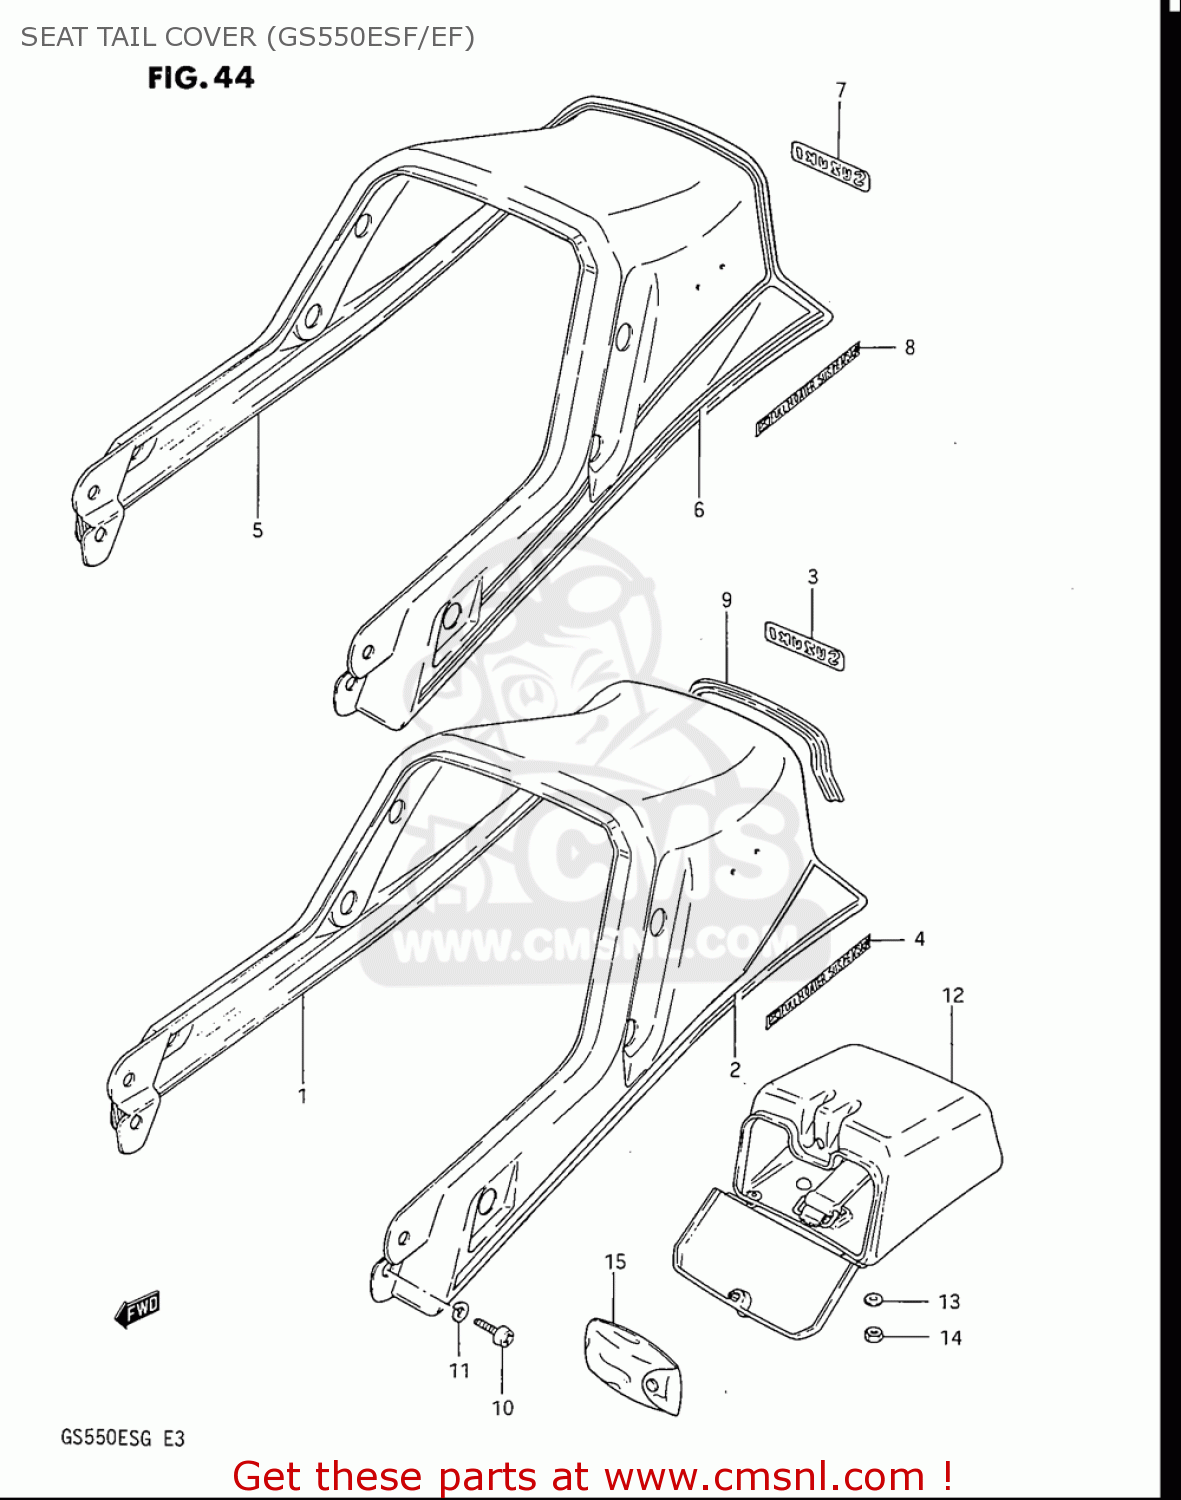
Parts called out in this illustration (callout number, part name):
3	EMBLEM(WHITE)
7	EMBLEM(WHITE)
10	SCREW
11	WASHER,LOCK
13	WASHER
14	NUT
15	TOOL ASSY
